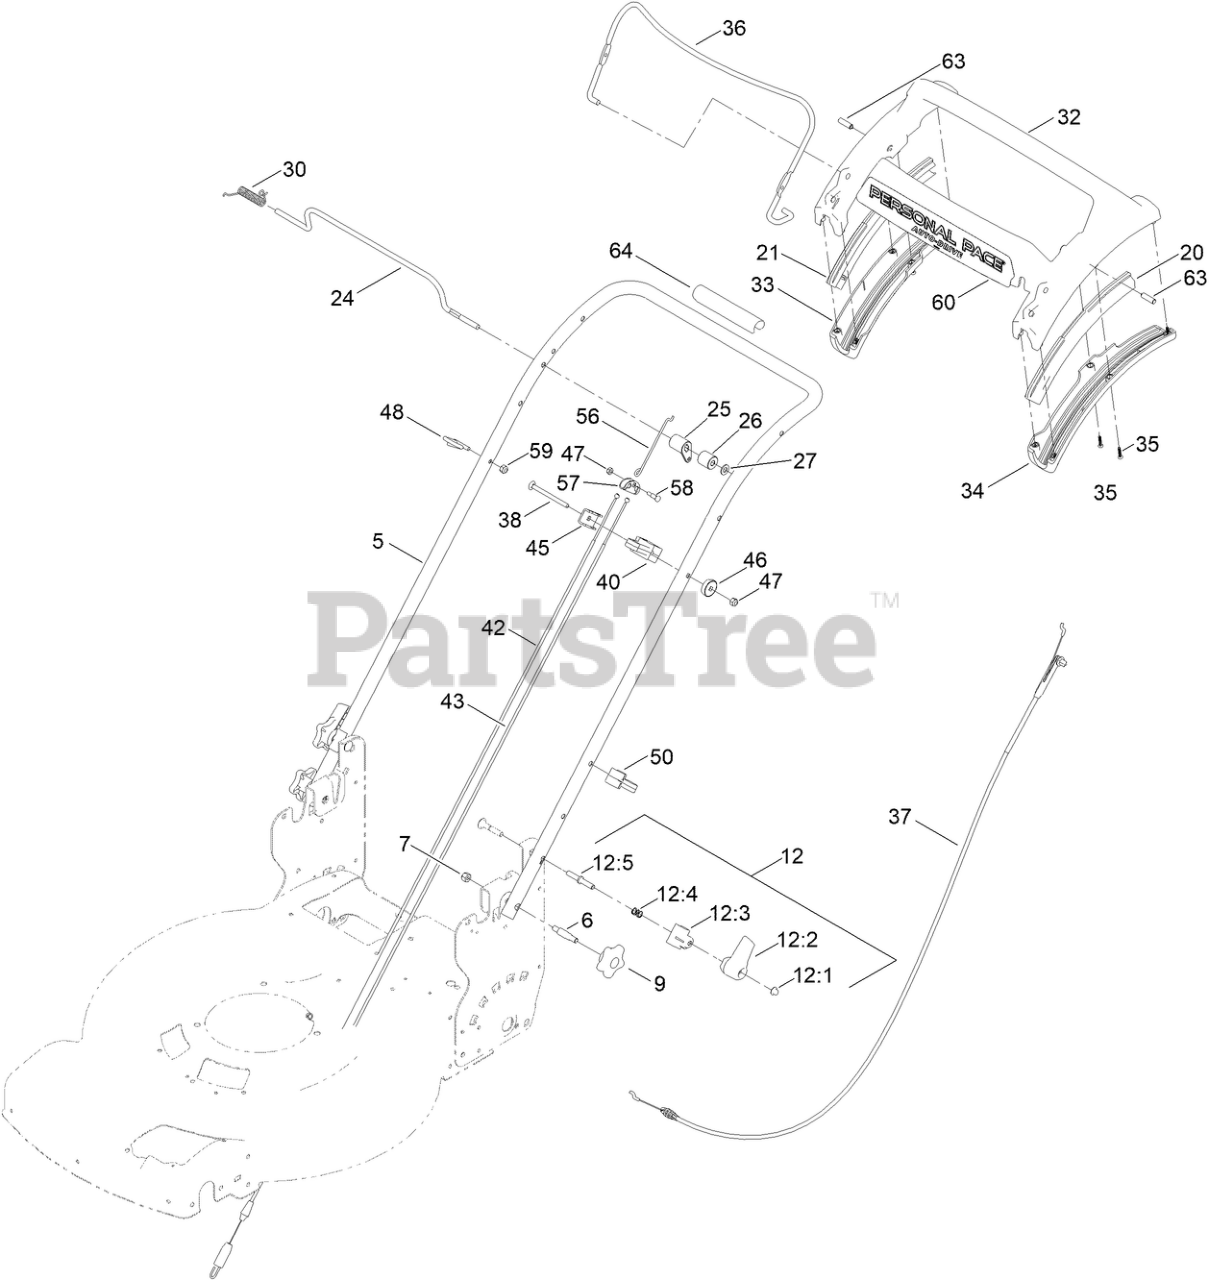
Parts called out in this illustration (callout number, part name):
5	HANDLE-CURVED, AWD
6	BOLT-SHOULDER, HANDLE
7	NUT-HEX
9	KNOB-HANDLE
12	QUICK RELEASE ASM
12:1	NUT-PUSH
12:2	LEVER-RELEASE
12:3	ANCHOR-SPRING
12:4	SPRING-COMPRESSION
12:5	ROD-RELEASE
20	GUIDE-CURVED, LH (RWD)
21	GUIDE-CURVED, RH (RWD)
24	ROD-CONTROL, TRACTION
25	LEVER-TRACTION, AWD
26	SPACER-LEVER, TRACTION
27	WASHER-PLAIN
30	SPRING-TORSION
32	HANDLE-PERSONAL PACE, CURVED
33	BOTTOM-HANDLE, RH
34	BOTTOM-HANDLE, LH
35	SCREW-PPH
36	BAIL-BRAKE
37	CABLE-BRAKE, PP BS
38	SCREW-CARR
40	ANCHOR-CABLE, AWD
42	CABLE-TRACTION, FRONT (AWD)
43	CABLE-TRACTION, REAR (AWD)
45	CLAMP-CABLE
46	WASHER-CURVED
47	NUT-HEX
48	GUIDE-ROPE
50	GUIDE-CABLE
56	LINKAGE-EQUALIZER
57	YOKE-CABLE
58	BOLT-EQUALIZER
59	NUT-HEX
60	DECAL - ADS, HANDLE
63	PIN-HANDLE, PP
64	HANDLE-COVER
